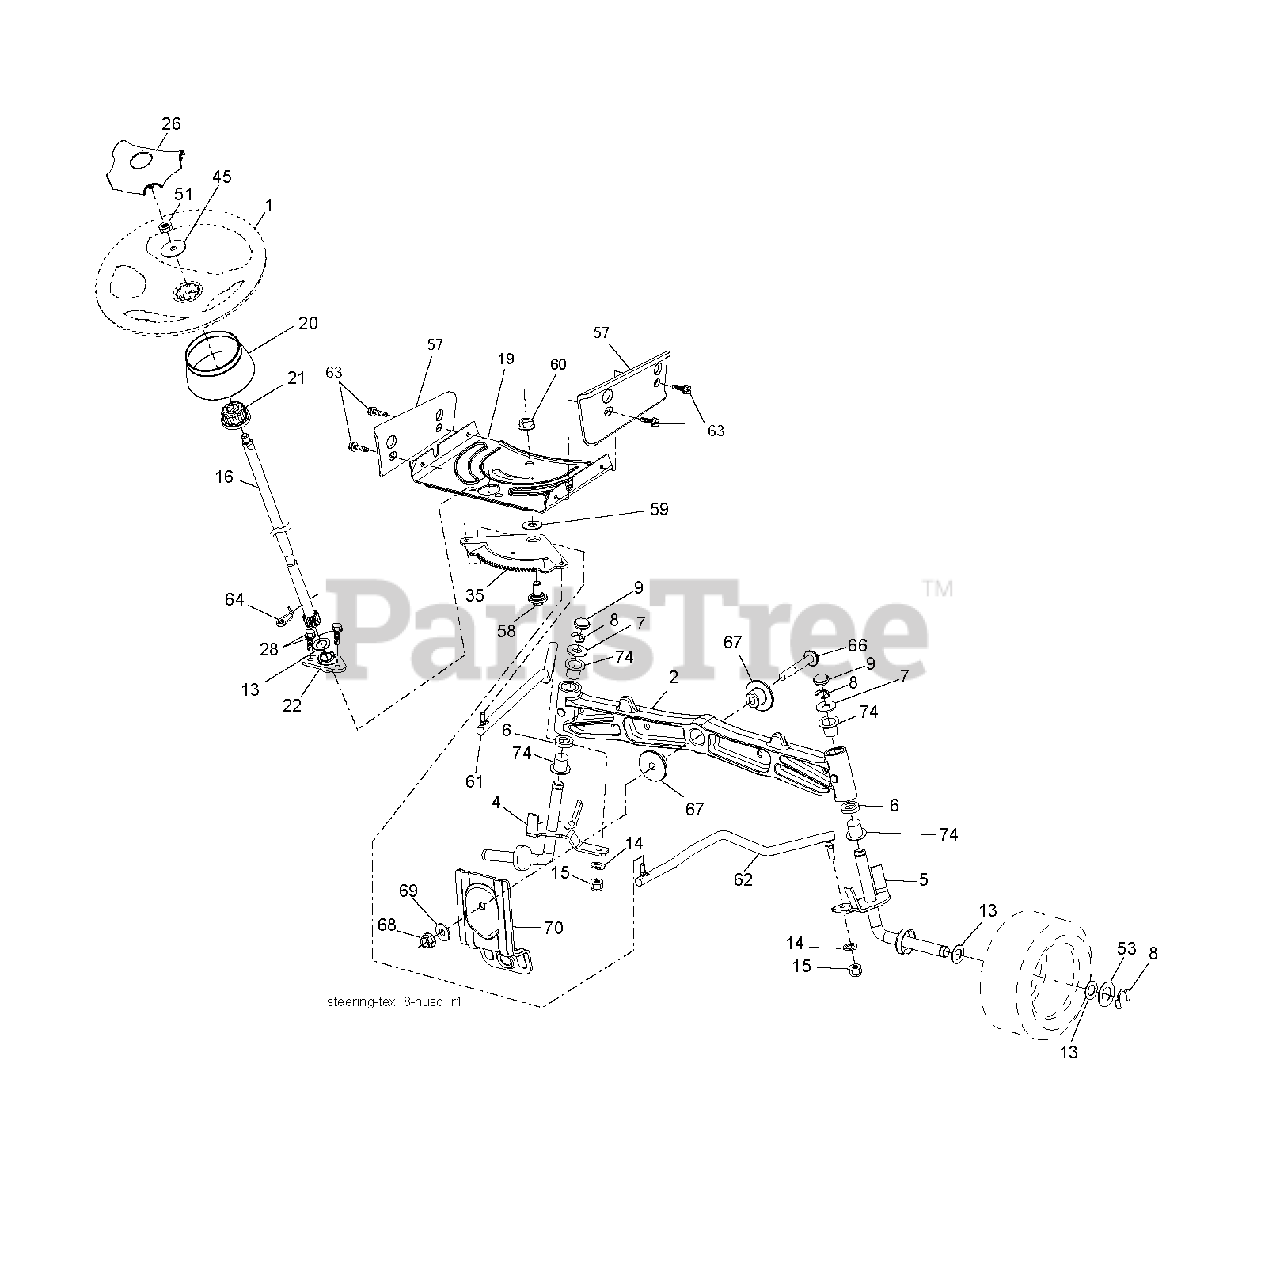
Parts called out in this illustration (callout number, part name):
1	WHEEL.STEERING.STDSRR.BLK/OV
2	AXLE.SVC.ASM CAST IRON.TEX
4	SPINDLE.WELDED.LH.15"TEX
5	SPINDLE.WELDED.RH.15"T
8	RING CLIP
9	CAP.SPINDLE
14	WASHER, LOCK 3/8
15	NUT CROWNLOCK 3/8-24
16	SHAFT.STEER.STEALTH.DD
19	PLATE.STEER.DDL.NLT/NG
21	ADAPTER, WHEEL STNG..
22	BUSHING.ASM.STEERING.A
26	CAP.WHL.STRNG.STDSRRD.SRS.BLK
28	SCREW, 3/8-16X3/4
35	GEAR.SECTOR.PLATE.DDL.
45	WASHER 9/16"ID, 2 3/8"OD
51	NUT.HEX.1/2-20
53	WASHER.HARDENED
57	BRACKET.UPSTOP.TEX
58	BOLT.SHOULDER.SECTOR.P
59	WASHER.THURST.SECTOR.S
60	NUT FLANGE LOCK 5/8-11
61	DRAGLINK.LH.BALLSTUD.D
62	DRAGLINK.RH.BALLSTUD.D
63	SCREW
64	RETAINER.CLIP.SPRING.S
66	BOLT HEX FGHD 7/16-14 X 3 SERR
67	BUSHING.PM.FRONT AXLE
68	NUT.LOCK.FLANGE.7/16
69	WASHER.1.5X.505X.118
70	BRKT.DECK.SUSPENSION.F
74	BUSHING, AXLE CAST
